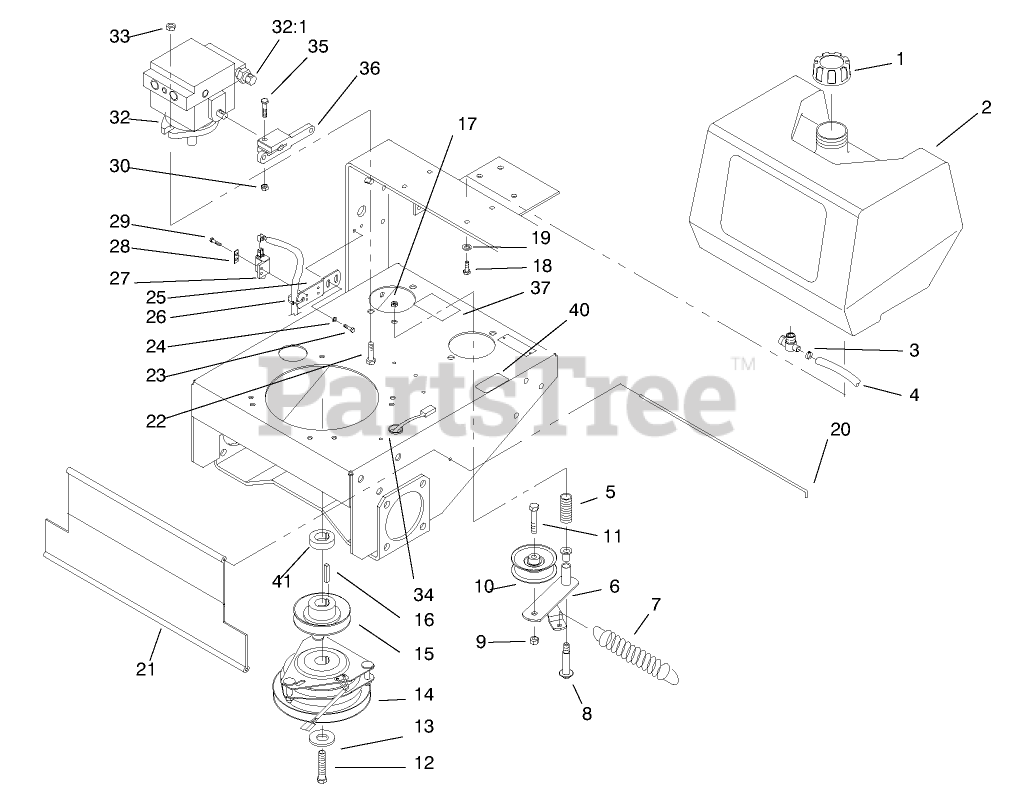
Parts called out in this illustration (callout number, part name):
1	GAS CAP ASM
2	TANK-FUEL
3	CLAMP-HOSE
4	GAS HOSE
5	SPRING-COMPRESSION
6	Lever-Idler
7	SPRING
8	BOLT-WHEEL
9	NUT-LOCK, NI
10	Pulley-Idler
11	SCREW-HH
12	SCREW-HH
13	WASHER
14	CLUTCH/BRAKE
15	Pulley
17	NUT-LOCK
18	SCREW-HH
19	WASHER-LOCK
20	ROD-SHIELD
21	SHIELD-TRAILING
22	SCREW-HH
23	Screw
24	WASHER-FLAT
25	Bracket-Neutral
26	TIE-CABLE
27	SWITCH-POLE, SINGLE
28	PLATE-SWITCH
29	SCREW-TAPTITE
30	NUT-LOCK, NI
32	HYD PUMP ASM
32:1	ASSEMBLY - VALVE
33	NUT-HF
34	GROMMET
35	SCREW-HH
36	ARM-PUMP
37	DECAL-ADJUSTMENT, VALVE
41	SPACER - PULLEY
